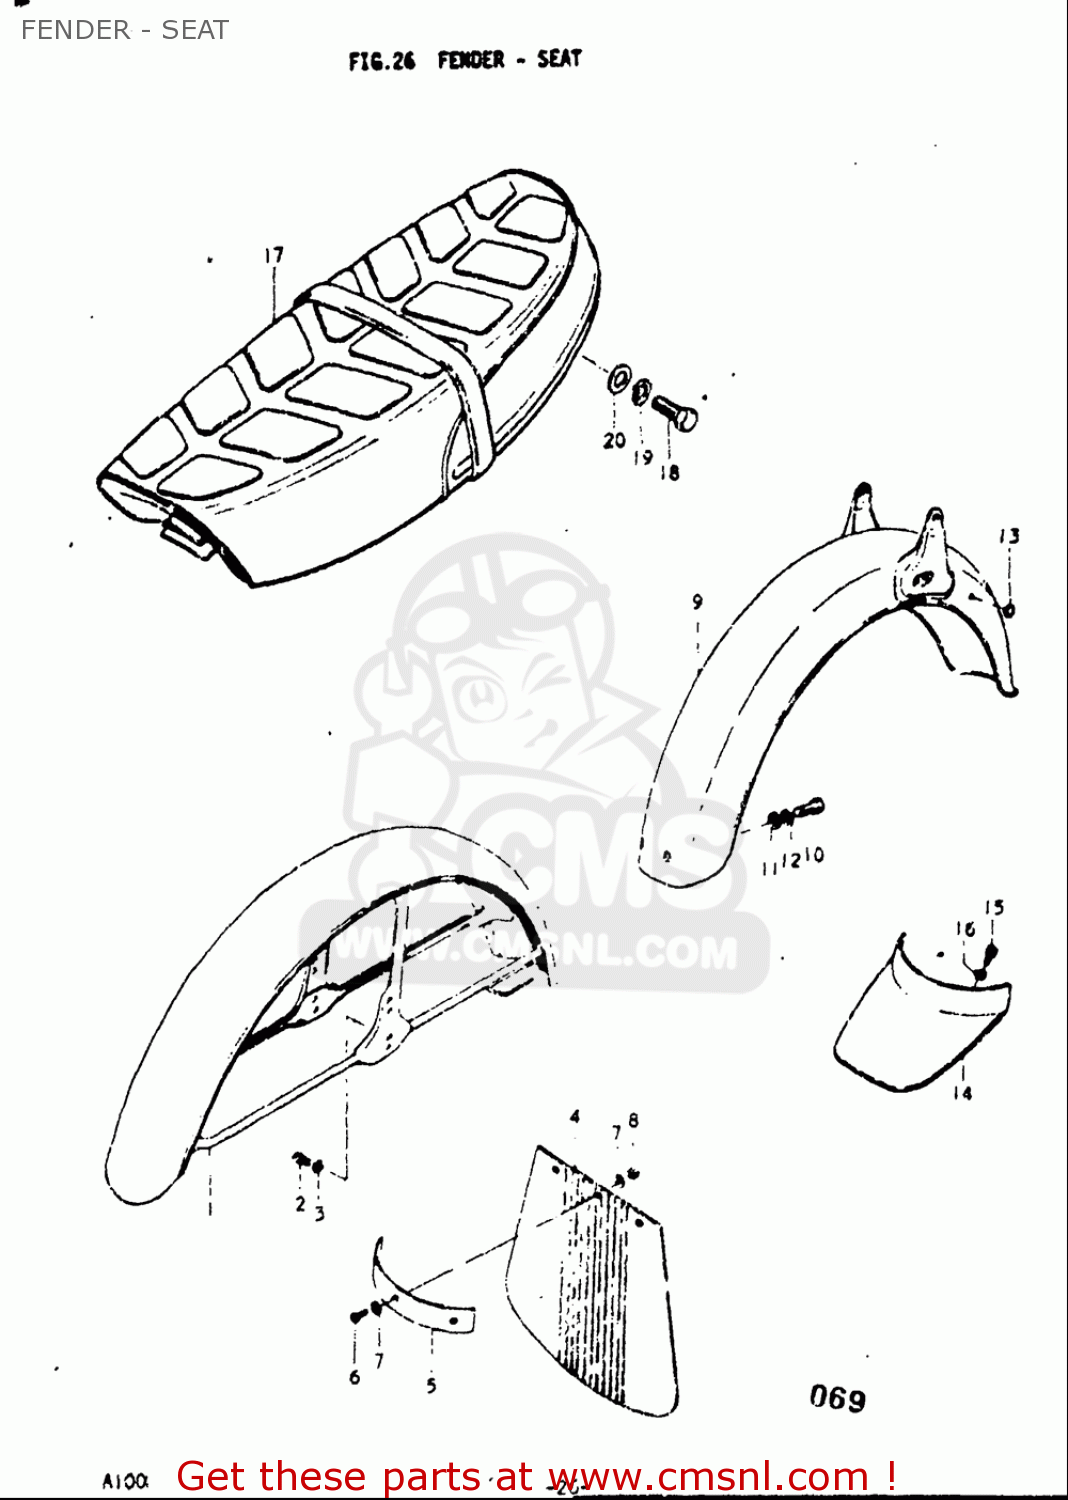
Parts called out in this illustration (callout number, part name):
2	BOLT
3	WASHER,LOCK
4	GUARD,MUD
6	SCREW
7	WASHER
8	NUT
9	FENDER,RR
10	BOLT
11	WASHER
12	WASHER,LOCK
15	BOLT
16	WASHER,LOCK
18	BOLT
19	WASHER,LOCK
20	WASHER
